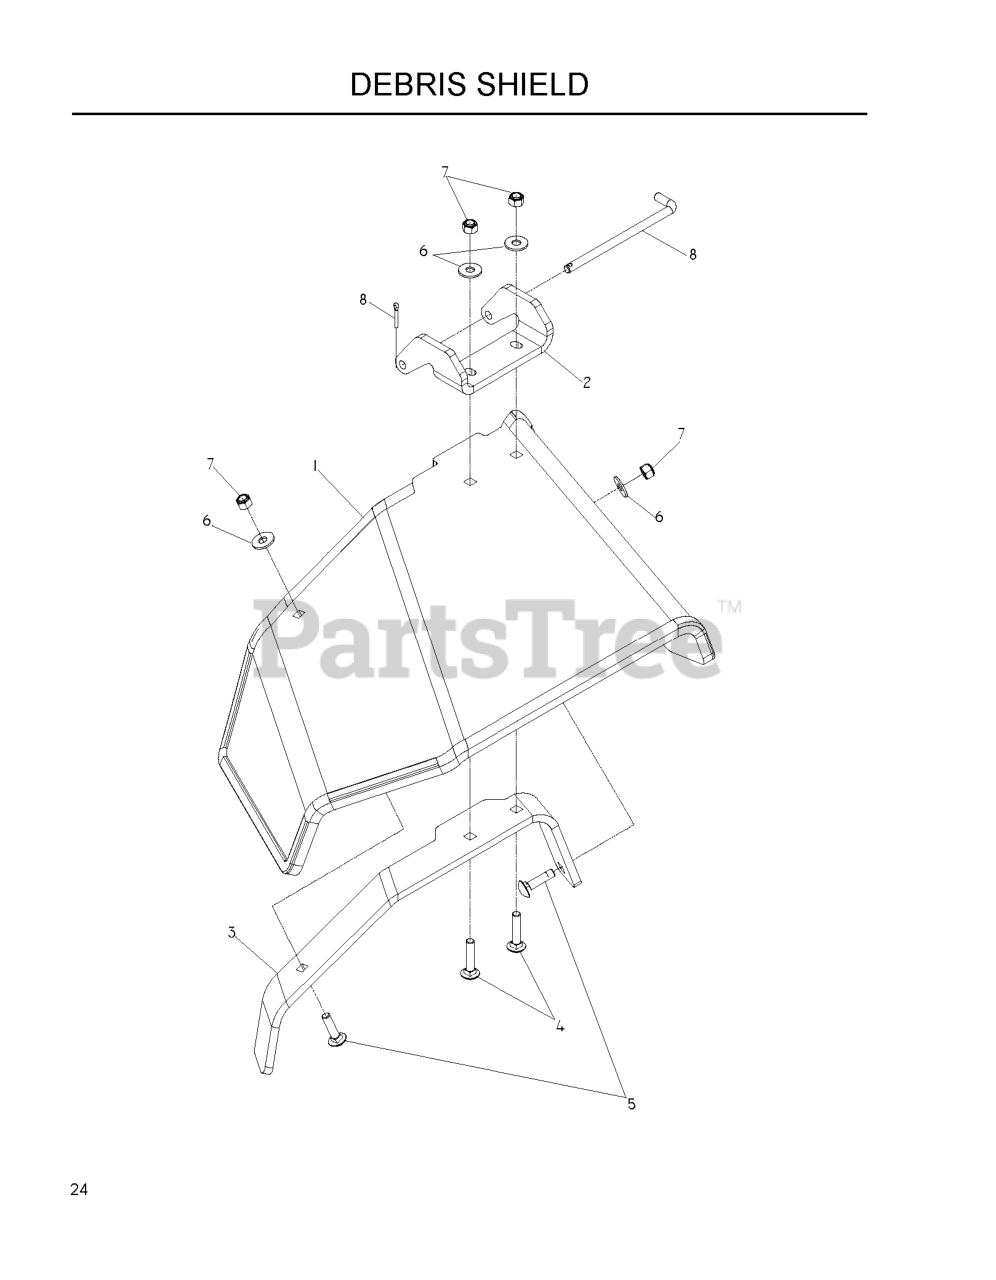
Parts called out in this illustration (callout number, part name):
1	CHUTE, RUBBER DISCHARGE 52/61"
2	PIVOT BRACKET - RUBBER CHUTE
3	BRACKET, REINF-CHUTE
4	RHSNB 5/16-18 X 1-1/2 GR 5 ZD
5	BOLT, CARRIAGE 5/16X1-1/4
6	WASHER 5/16 FLAT
7	NUT 5/16 NYLOC
8	PIN, CHUTE PIVOT
